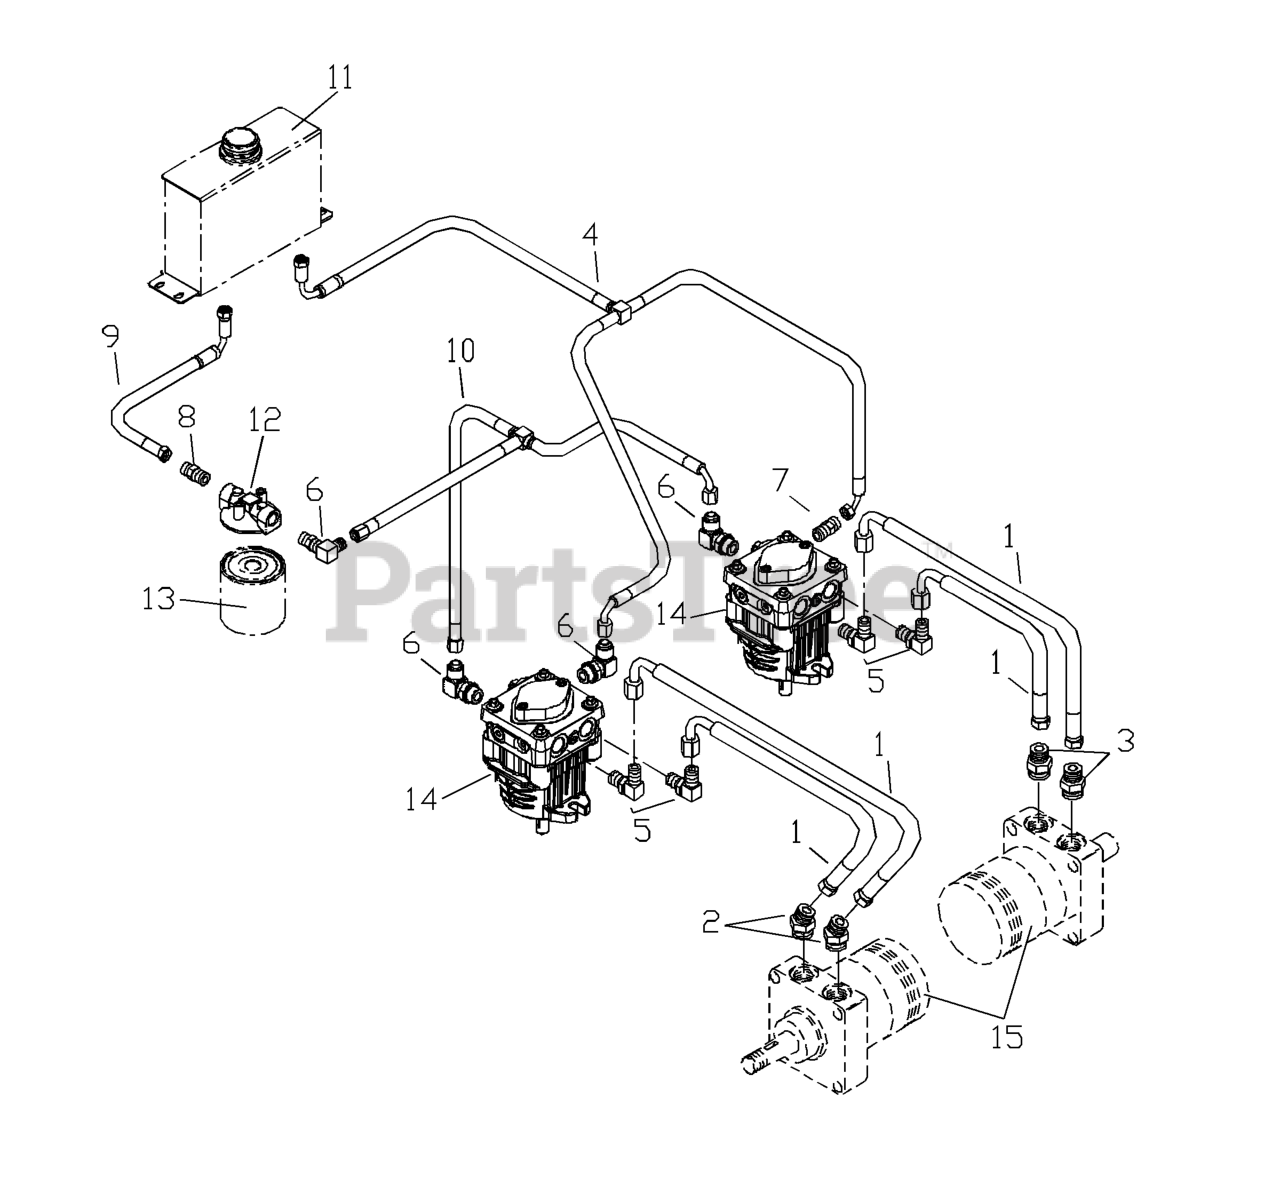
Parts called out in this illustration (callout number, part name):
1	HOSE, 1/2" HYDRAULIC
2	ELBOW-ADJ 45 DEG F6802-8-10
3	CONNECTOR, STRAIGHT
4	INLET TEE HOSE
5	ELBOW, 90 DEGREE
6	ELBOW, F6801-6-6-0 90 DEGREE
8	STRAIGHT FITG
9	HOSE
10	RETURN TEE HOSE
11	OIL TANK BLK
12	FILTER HEAD
13	HYDRAULIC OIL FILTER
14	PUMP
15	WHEEL MOTOR
